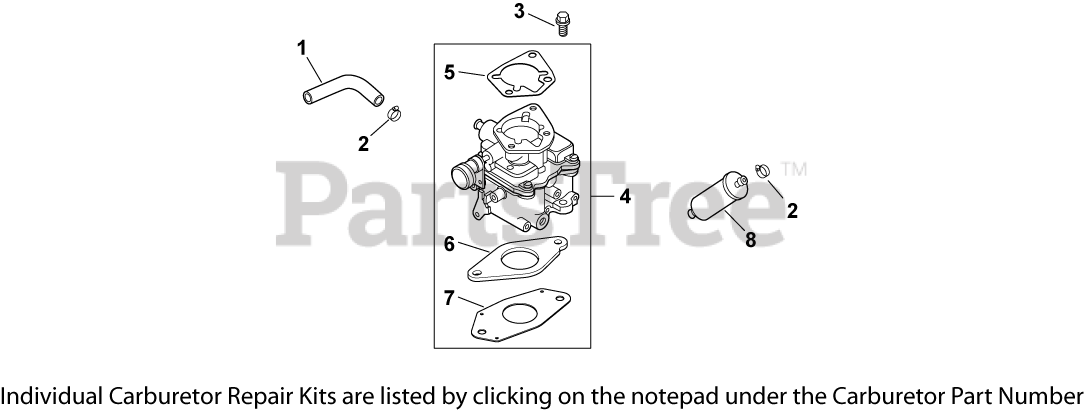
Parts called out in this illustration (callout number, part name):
1	HOSE,LW PERM.FUEL 24.00"-USE 25 111 81-S
2	CLAMP, HOSE (KM)-USE 25 237 31-S
3	SCREW, FLG M6X1.0X30
4	KIT, CARBURETOR W/GASKETS
5	GASKET, AIR CLEANER BASE
6	GASKET, CARBURETOR
7	GASKET, CARBURETOR
8	FILTER, FUEL
